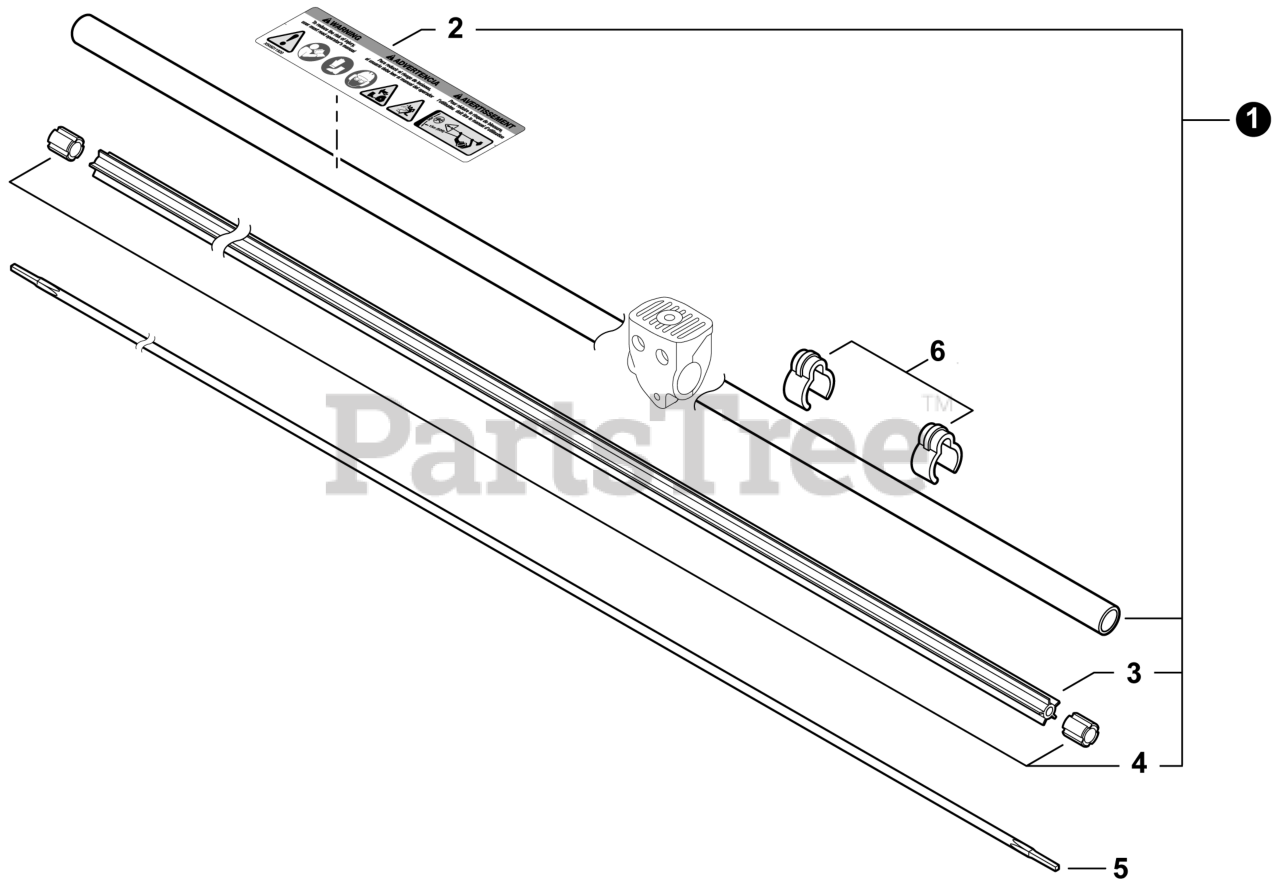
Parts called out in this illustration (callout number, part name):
1	MAIN PIPE ASSY
2	LABEL - CAUTION ISO
3	LINER, FLEXIBLE
4	STOPPER
5	DRIVESHAFT - FLEXIBLE
6	CLIP, CABLE 25 MM
